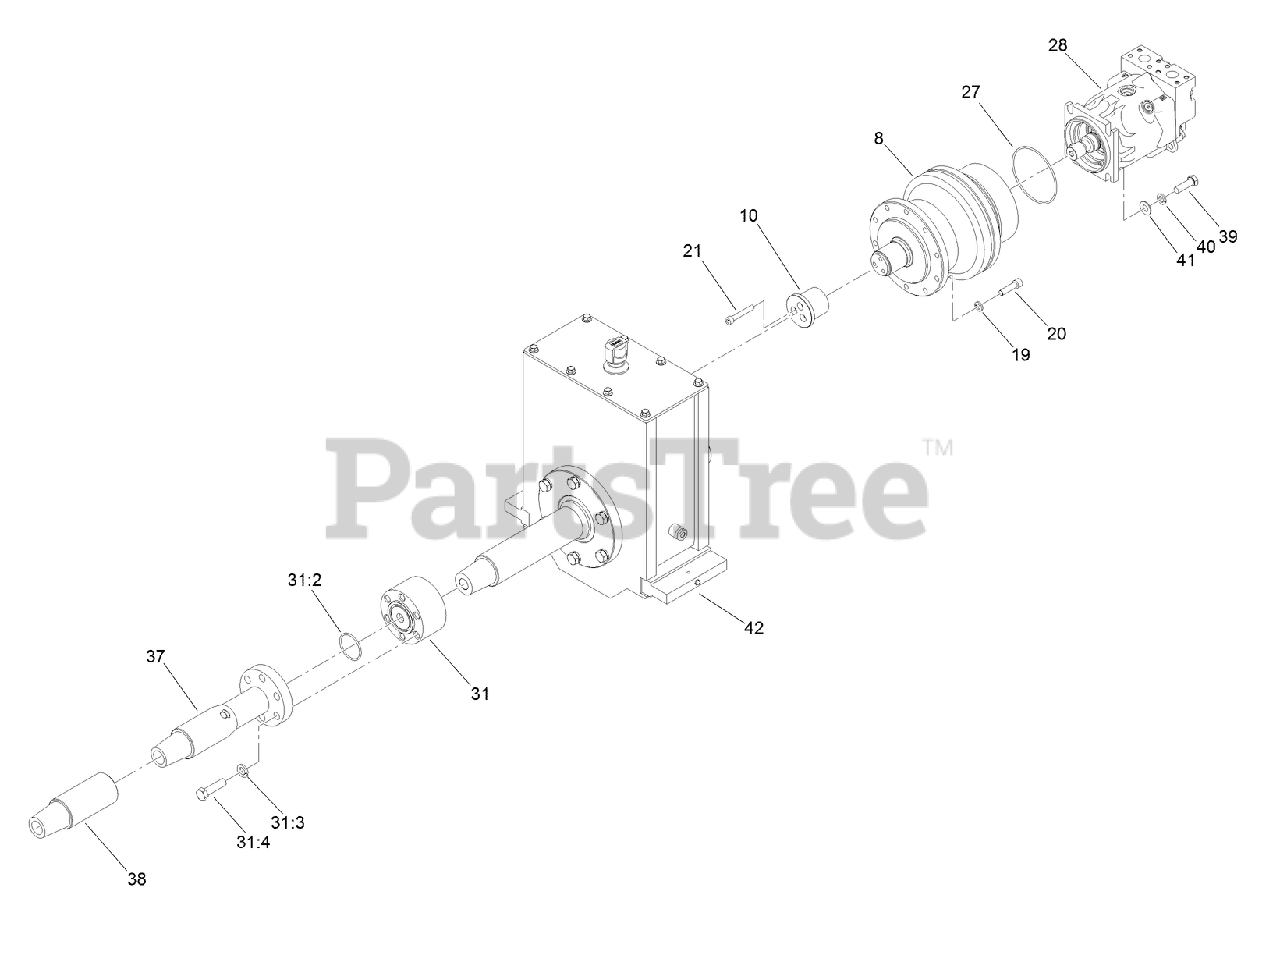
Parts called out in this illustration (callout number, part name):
8	PLANETARY GEARBOX ASM
10	CAP-PINION, ROTARY
19	WASHER-LOCK
20	SCREW-HSFH
21	SCREW-HSH
27	O-RING
28	HYD MOTOR ASM
31	SPINDLE ASM
31:2	O-RING
31:3	WASHER-LOCK
31:4	SCREW-HH
37	ADAPTER-FLANGE
38	SAVER ASM
39	SCREW-HH
41	WASHER
42	ROTARY BOX ASM
